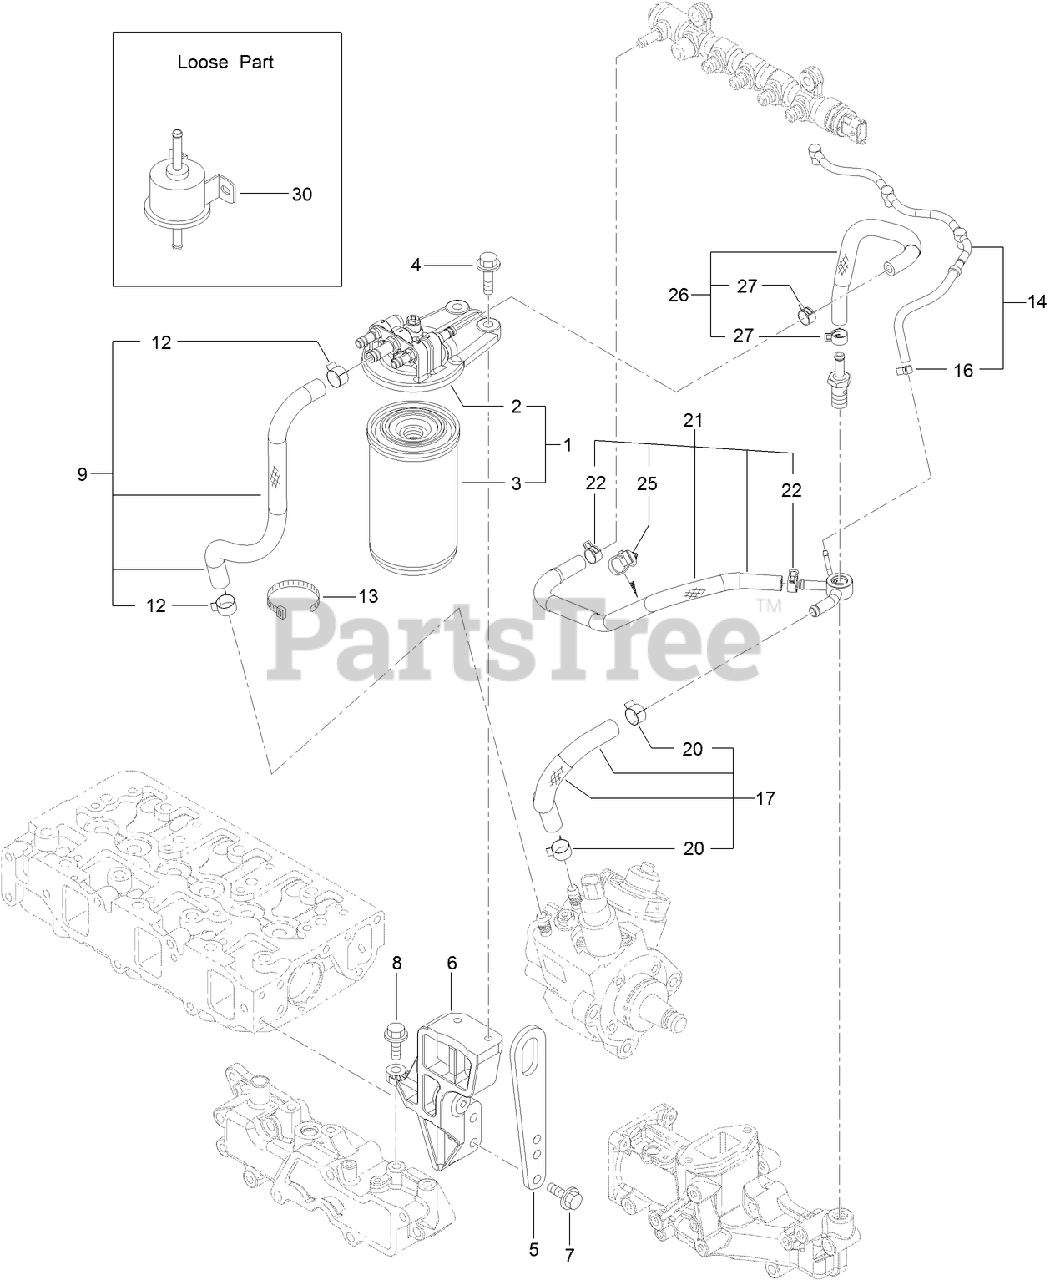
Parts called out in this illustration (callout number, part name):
1	FUEL/OIL FILTER ASM
2	FUEL/OIL FILTER BRACKET ASM
3	FILTER-FUEL/OIL
5	LIFTER
6	FILTER BRACKET ASM
9	FUEL PIPE ASM
12	CLAMP-HOSE
14	FUEL/OIL RETURN PIPE ASM
16	CLAMP-HOSE
17	FUEL PIPE ASM
20	CLAMP-HOSE
21	FUEL PIPE ASM
22	CLIP-HOSE
25	BAND-CLIP
26	FUEL PIPE ASM
27	CLIP-HOSE
30	FUEL FEED PUMP ASM
